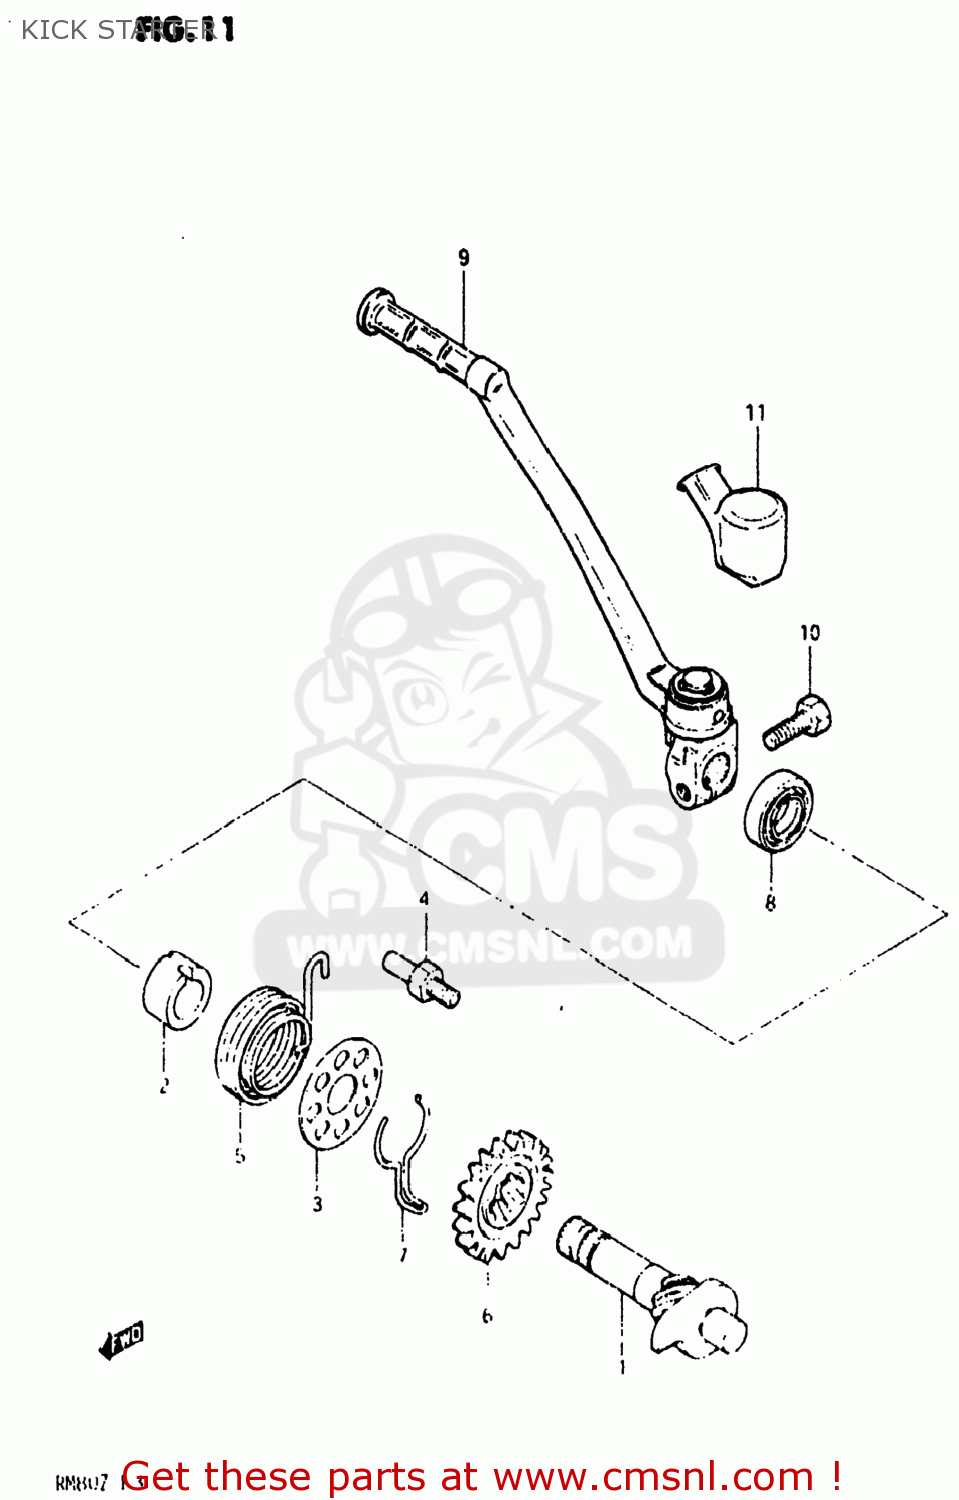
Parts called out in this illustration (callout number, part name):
1	SHAFT,KICK STARTER
2	GUIDE,KICK STARTER SFT SPRING
3	HOLDER,KICK STARTER SHAFT SPR
4	BOLT,KICK START SHAFT SPR HOOK
5	SPRING
6	GEAR,KICK STARTER DRIVE
7	SPRING,RETAINER
8	SEAL,OIL(14X24X6)
9	LEVER ASSEMBLY,KICK STARTER
10	BOLT
11	COVER,KICK LEVER JOINT
